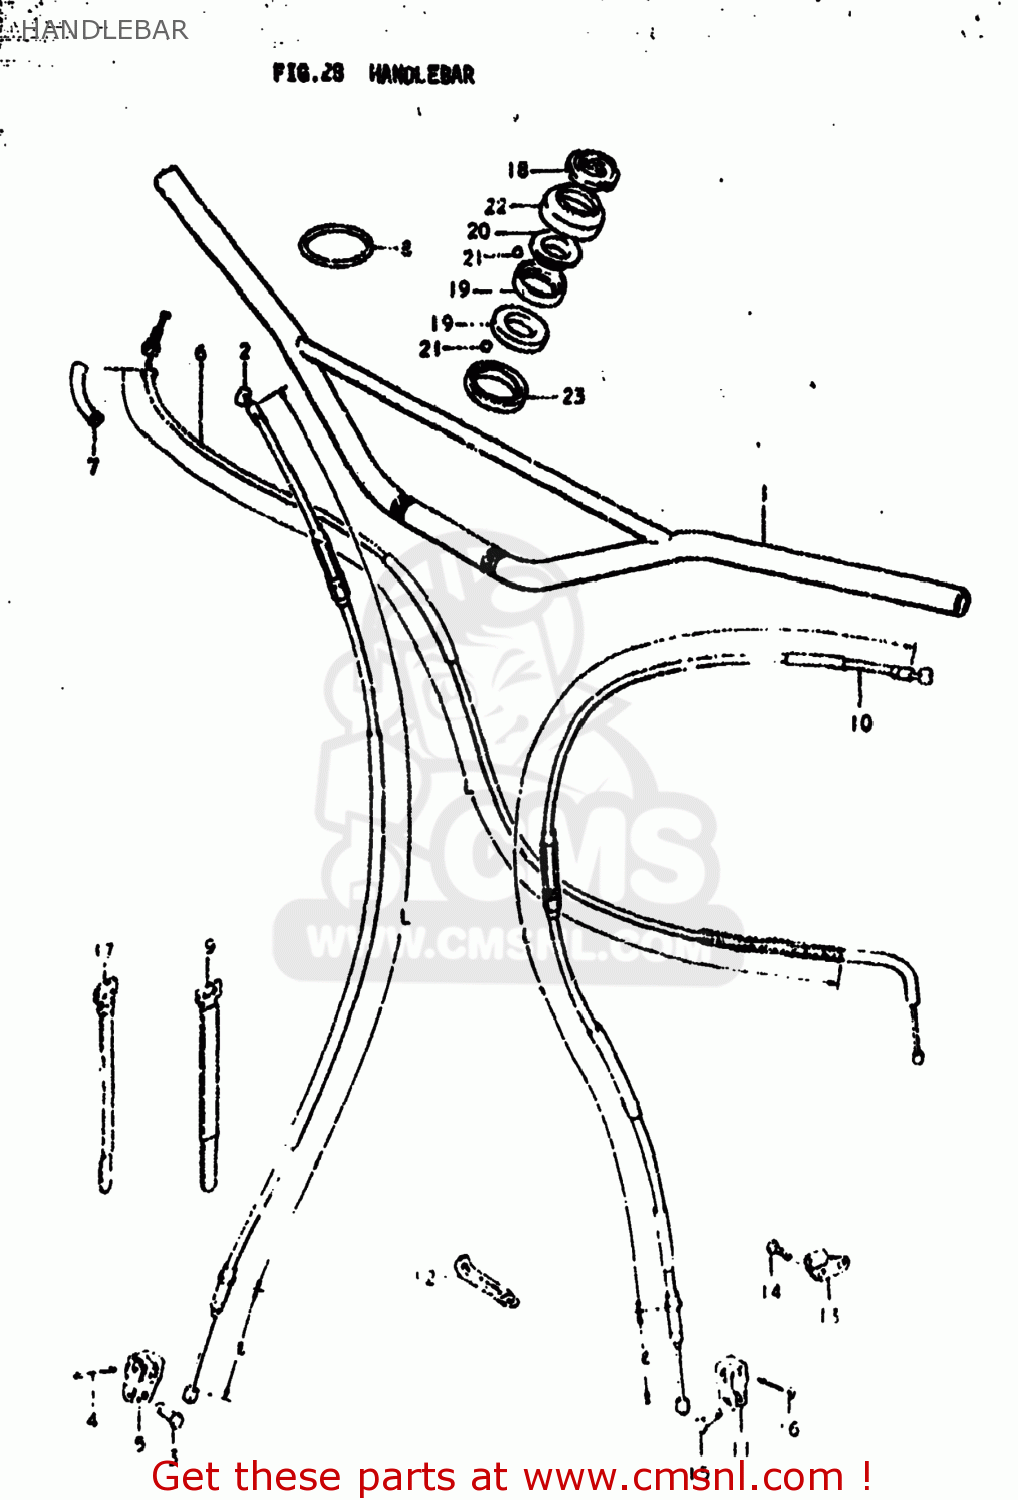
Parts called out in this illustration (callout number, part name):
1	HANDLEBAR
2	CABLE,FRONT BRAKE
3	PIN(L:13.5)
4	PIN
5	BRAKE CABLE HOOK
6	CABLE ASSEMBLY,THROTTLE
7	DUST, SEAL
8	O RING,RR BRAKE CABLE
9	CLAMP
10	CABLE ASSEMBLY,CLUTCH
11	HOOK,CLUTCH CABLE
12	CLAMP L:35
13	STOPPER,CLUTCH CABLE
14	SCREW
15	PIN(L:13)
16	PIN
17	CLAMP(L:120)
18	NUT,STEERING STEM(25X44X10)
19	LACE,STEERING INNER LWR
20	LACE,STEERING OUTER UPR
21	BALL
22	DUST SEAL,STEERING,UPPER
